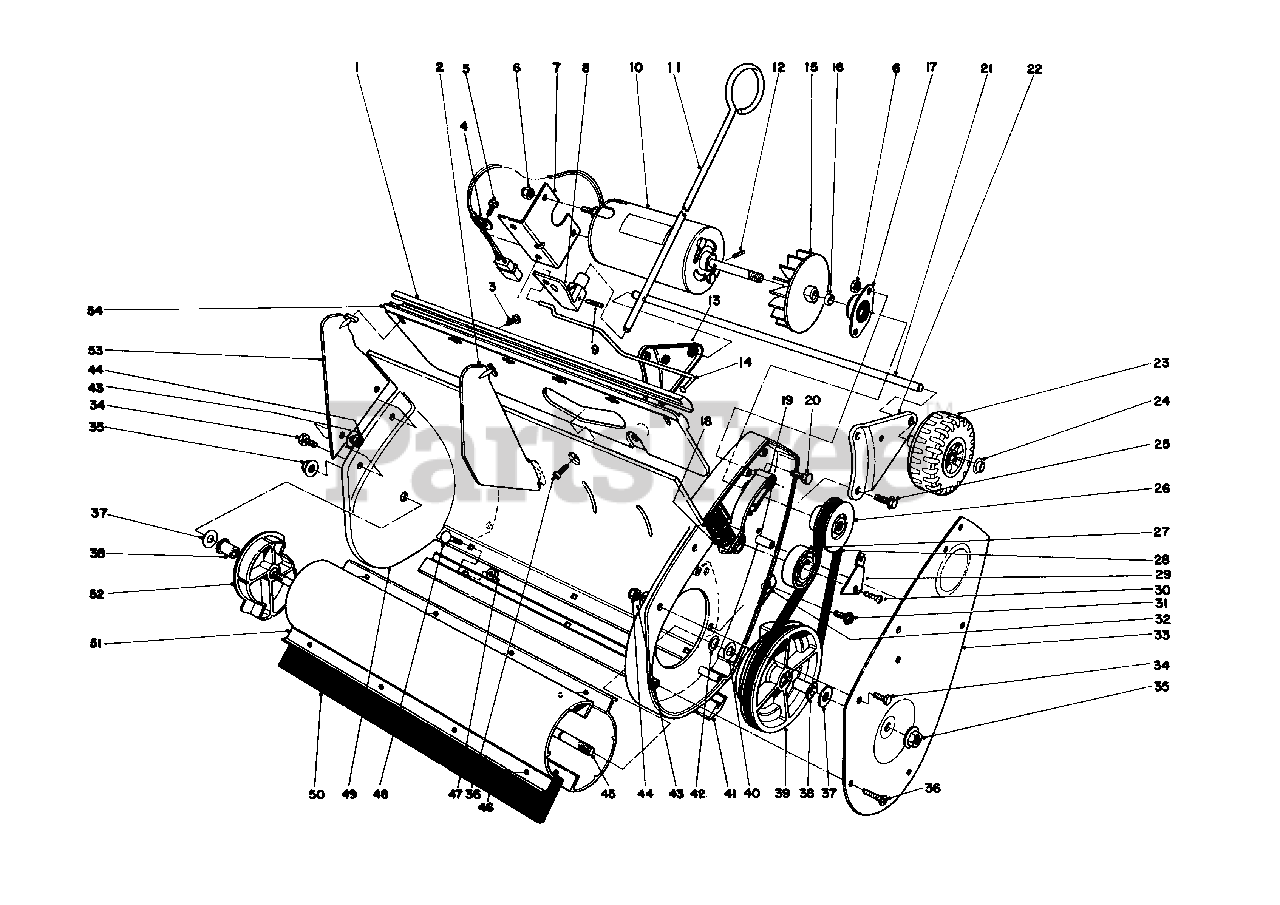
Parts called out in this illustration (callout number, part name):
1	Moulding
2	Vane-Inner
4	Insulated Closed Clip
7	Bracket-Mounting
8	Bracket-Vane Adjustment
9	Groove Pin
11	Rod-Vane Adjustment
12	Spring Pin
13	Wheel Bracket R.H.
14	Linkage Vane Adjustment
17	Bearing-Flanged
18	Idler Spring
19	Idler Arm
21	Axle Shaft
22	Wheel Bracket L.H.
24	Push Nut
25	Screw
26	Drive Pulley
27	Ball Bearing
28	Drive Belt
29	Retainer-Idler Pulley
32	Tinnerman Nut
33	Cover-Belt Case
37	Thrust Washer
38	Rotor Bushing
39	Pulley-Driven
40	Thrust Washer
42	Retaining Ring
43	Washer
45	Shaft-Rotor
46	Screw-Thread Forming
48	Carriage Bolt
50	Blade-Rotor
52	End Cap Rotor
53	Vane-Outer
54	Vane-Mount
